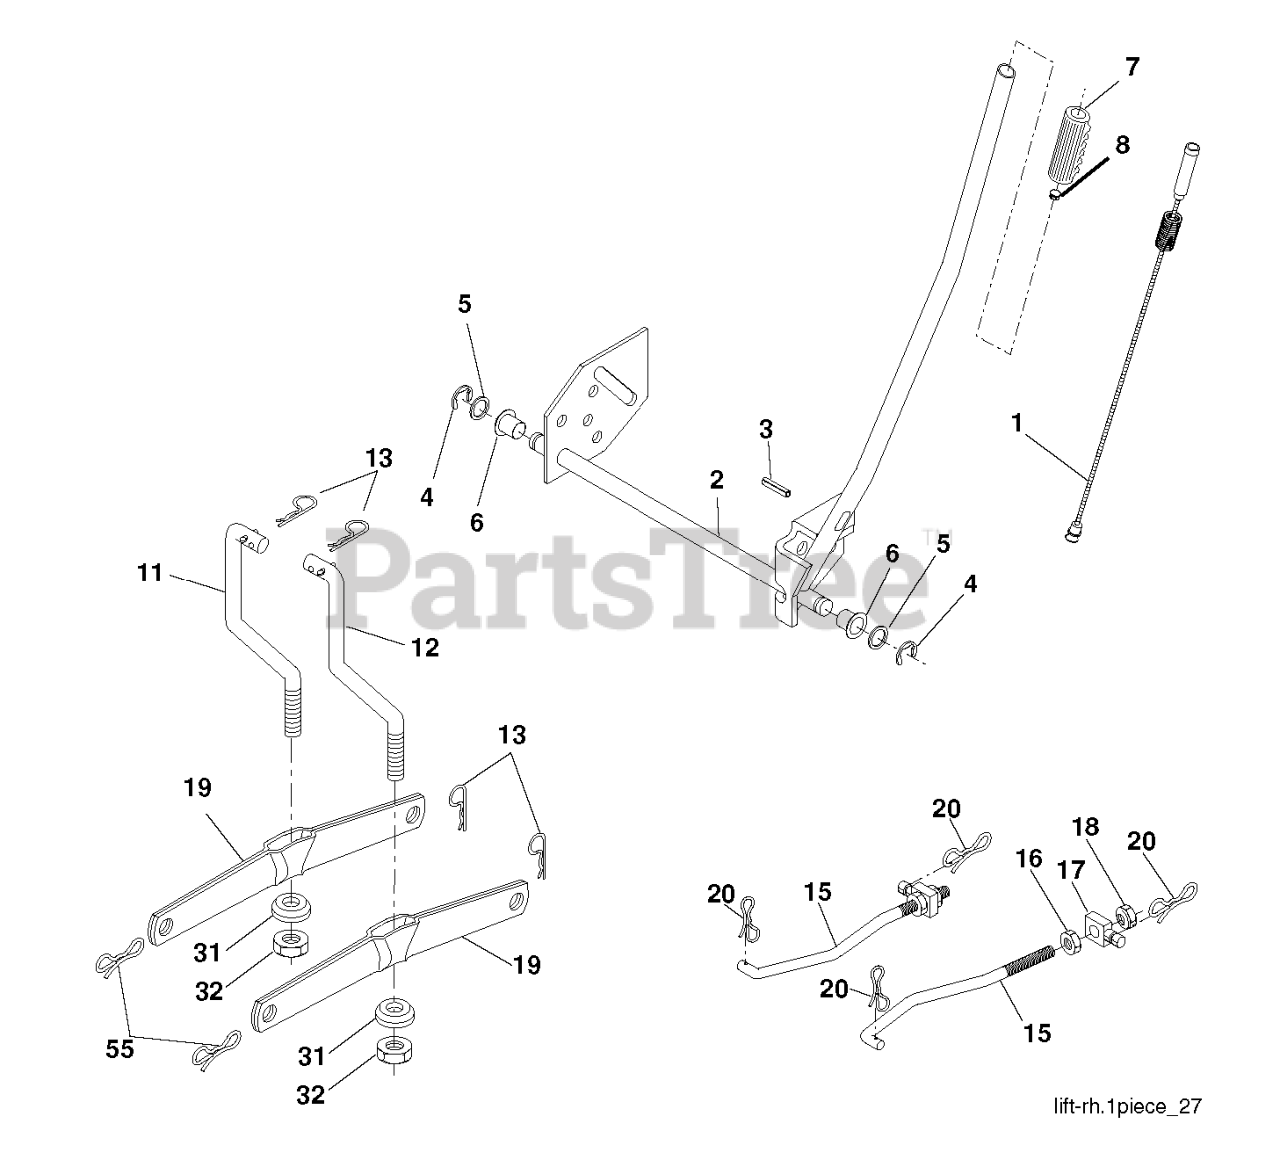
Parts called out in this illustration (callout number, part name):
1	PLUNGER.ASM.LIFT.LVR.BLK.17.32
2	SHAFT ASM R HANDLE
3	PIN GROOVE.
4	RETAINING RING LT
6	BEARING.NYLON
8	PLUNGER BUT KIT
11	LINK LIFT LH
12	LINK LIFT RH
13	RETAINER-SPRNG RB
15	LINK.SUSPENSION.FRONT
16	NUT.HEX.JAM.1/2-13
18	NUT.LK.W/WSH.1/2.
19	ARM.REAR.SUSPENSION
20	PIN.COTTER.7/16.BOW TI.
31	BEARING.PIVOT.LIFT
32	NUT CROWNLOCK 3/8-24
55	PIN.COTTER.5/16.BOW TI
